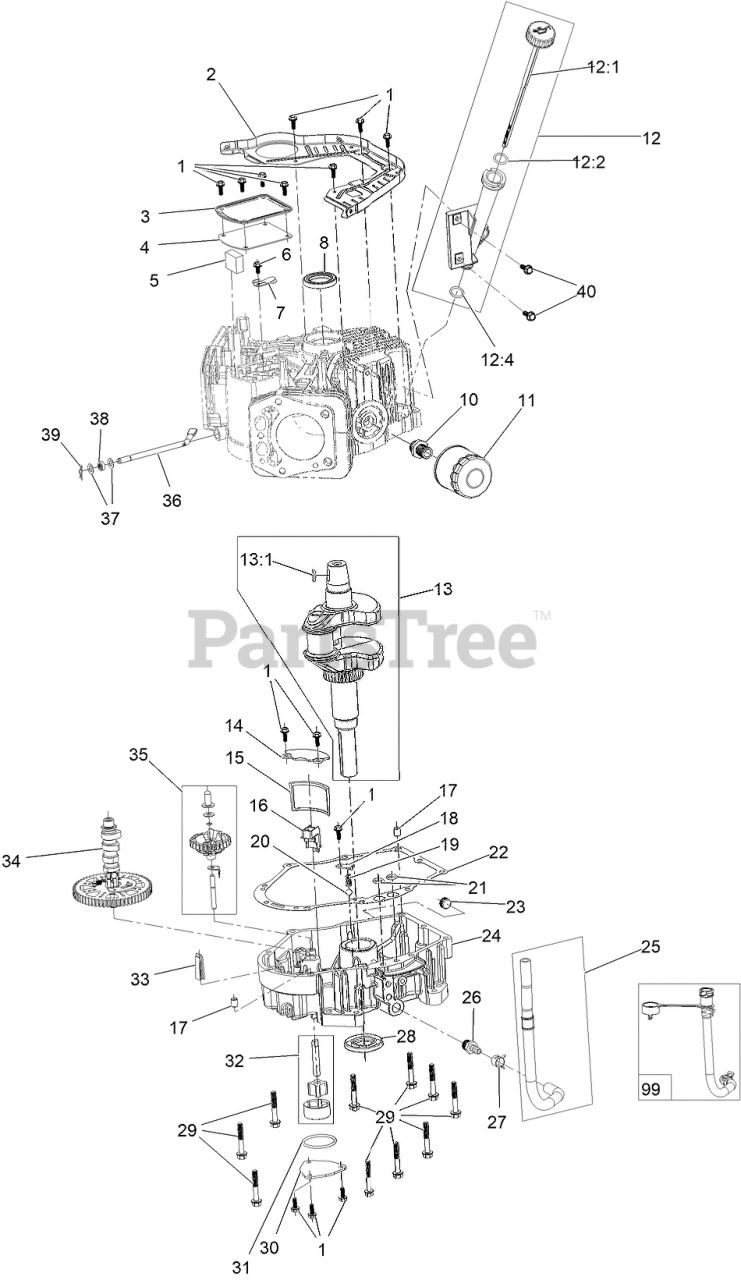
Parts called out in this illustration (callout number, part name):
1	SCREW-HHF
2	BAFFLE
3	COVER-BREATHER
4	GASKET-BREATHER
5	FILTER-BREATHER
6	SCREW-HHF
7	VALVE-BREATHER
8	SEAL-OIL
10	ADAPTOR-FILTER, OIL
11	FILTER-OIL
12	OIL TUBE ASM
12:1	DIPSTICK
12:2	O-RING
12:4	O-RING
13	CRANKSHAFT
13:1	KEY-WOODRUFF
14	COVER-SCREEN, OIL
15	SCREEN-OIL
16	RETAINER-SCREEN
17	PIN-DOWEL
18	PLATE-RETAINER
19	SPRING
20	VALVE-BALL
21	O-RING
22	GASKET-COVER, CRANKCASE
23	PLUG-DRAIN
24	COVER-CRANKCASE
25	OIL DRAIN HOSE ASM
26	FITTING-HOSE
27	CLAMP-HOSE
29	SCREW-HHF
30	COVER-OIL PUMP
31	O-RING
32	OIL PUMP ASM
33	DEFLECTOR-OIL, RUBBER
34	CAMSHAFT
35	GOVERNOR ASM
36	SHAFT-GOVERNOR
37	WASHER-PLAIN
38	SEAL-OIL
39	PIN-HAIR
40	SCREW-HHF
99	OIL DRAIN SERVICE KIT
